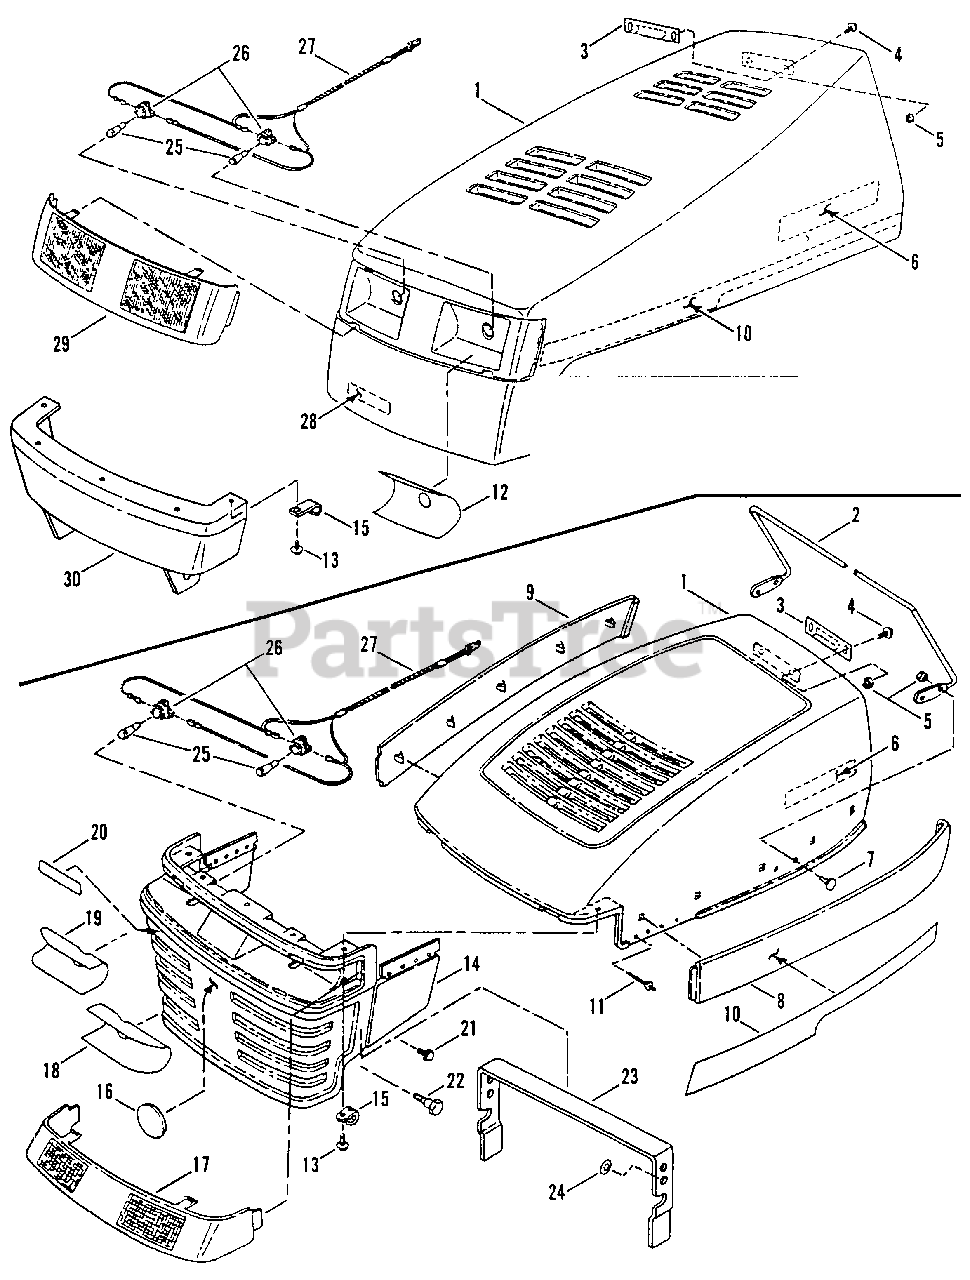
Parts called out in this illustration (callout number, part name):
1	HOOD
1A	HOOD, Mozart
2	ROD, Hood Support
3	LATCH, Spring
4	SCREW, 1/4-20 x 5/8" Truss Head, Torx
5	NUT, 1/4-20 Hex Nyloc
6	DECAL - SNAPPER, 8" Molded Logo, White Letters
6	DECAL - SNAPPER, 8" Molded Logo, Silver Letters
7	BOLT, 1/4-20 x 5/8" Flat Head Carriage, Grade 5
8	PANEL, Hood (Left Hand) (Black)
9	PANEL, Hood (Right Hand) (Black)
10	DECAL, Hood (Right Hand) (Hydro Drive)
10	DECAL, Hood (Left Hand) (Hydro Drive)
10	DECAL, Hood (Right Hand) (Gear Drive)
10	DECAL, Hood (Left Hand) (Gear Drive)
11	RIVET, 1/8" Pop
12	DECAL, Clear Lens (Left Hand) (Hydro Drive)
12	DECAL, Clear Lens (Right Hand) (Hydro Drive)
13	SCREW, M4.8 x 1.59 x 16.00MM, Special
14	GRILLE, Hood (Hydro Drive)
15	CLIP, "J"
16	DECAL, Molded Medallion
17	LENS, Grille (Headlights)
18	DECAL, Reflect (Left Hand) (Hydro Drive)
19	DECAL, Reflect (Right Hand) (Hydro Drive)
20	DECAL - SNAPPER, 4" Molded Logo (Silver Letters - Blue Stripe)
21	SCREW, 5/16-18 x 1/2" Self-Tapping, Grade 5
22	BOLT, Shoulder, 3/8-16 x 1-1/4" Hex Socket, Torx
23	BRACE, Hood Support
24	RETAINER, Bolt
25	BULB, Headlights
26	SOCKET, Headlight Bulb
27	HARNESS, Headlight Wiring
28	DECAL - SNAPPER, 4" Molded Logo (White Letters & Stripe)
29	LENS, Solid Black
29	LENS, Clear
30	BUMPER, Front Hood Support
